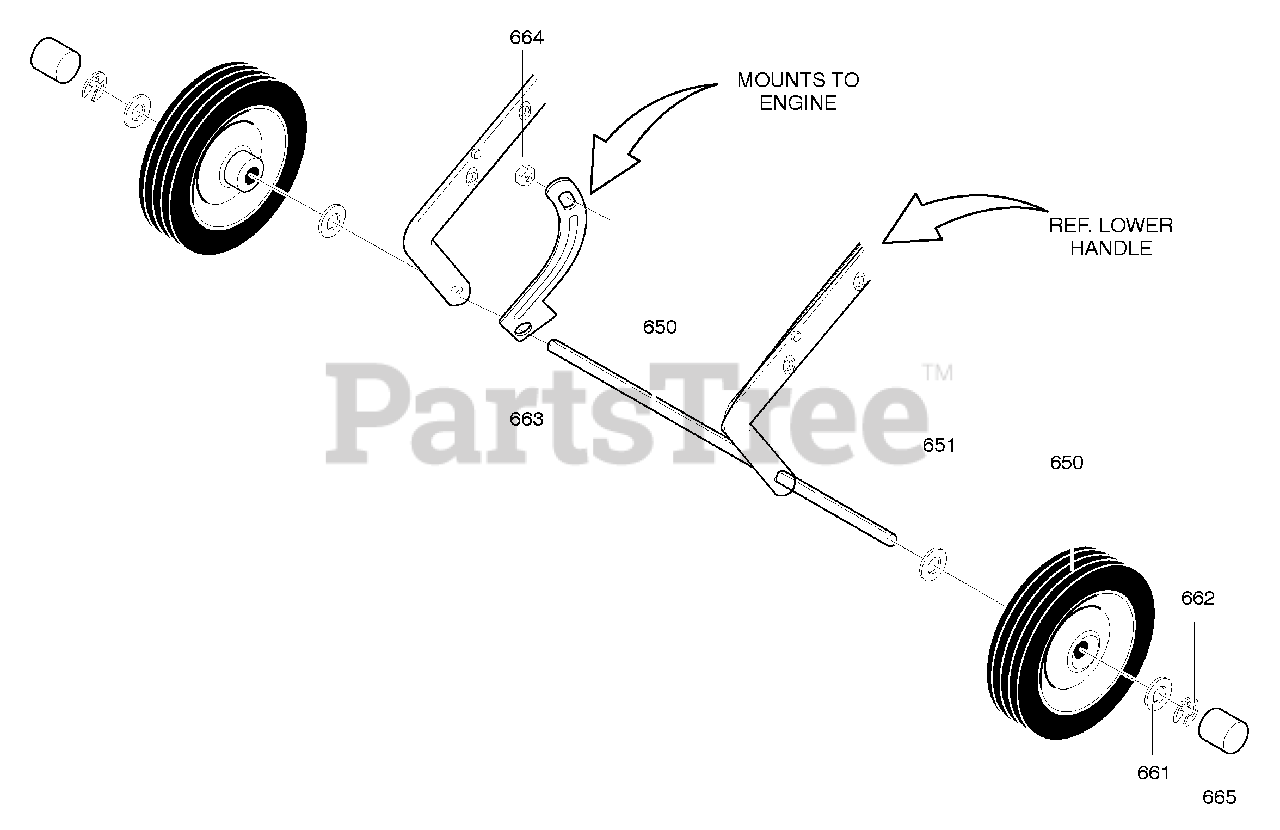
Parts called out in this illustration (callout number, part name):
650	AXLE SHAFT
651	WASHER, FLAT .391X1.00X1.25
660	TIRE & RIM
661	WASHER, FLAT .391X1..125
662	RING, RET E
663	BRACKET, AXLE
664	NUT
665	CAP, HUB
